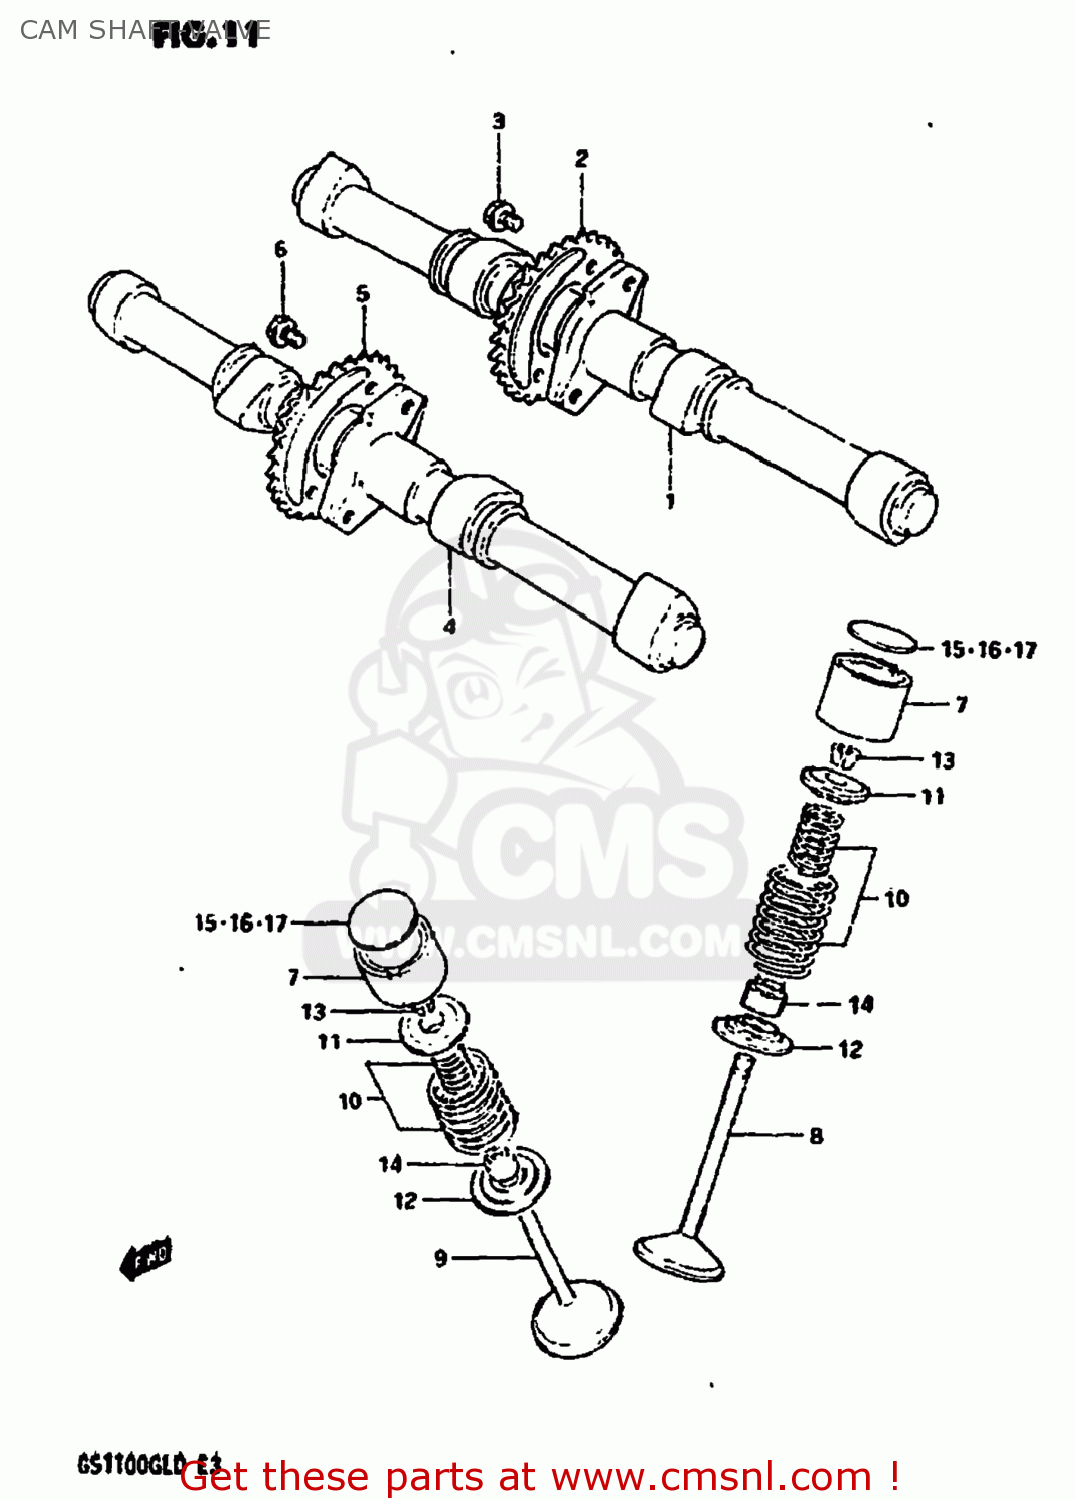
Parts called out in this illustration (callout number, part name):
1	CAMSHAFT,INTAKE
2	SPROCKET,INTAKE CAMSHAFT
3	BOLT(7X11)
4	CAMSHAFT,EXHAUST
5	SPROCKET,EXHAUST CAMSHAFT
6	BOLT(7X11)
7	TAPPET
8	VALVE,INTAKE
9	VALVE,EXHAUST
10	SPRING SET,VALVE
11	RETAINER,VALVE SPRING
12	SEAT,VALVE SPRING
13	COTTER VALVE
14	SEAL,OIL(7X14.4X9)
15	SHIM,TAPPET
16	SHIM,TAPPET
17	SHIM,TAPPET
18	SHIM SET,TAPPET
19	CASE
